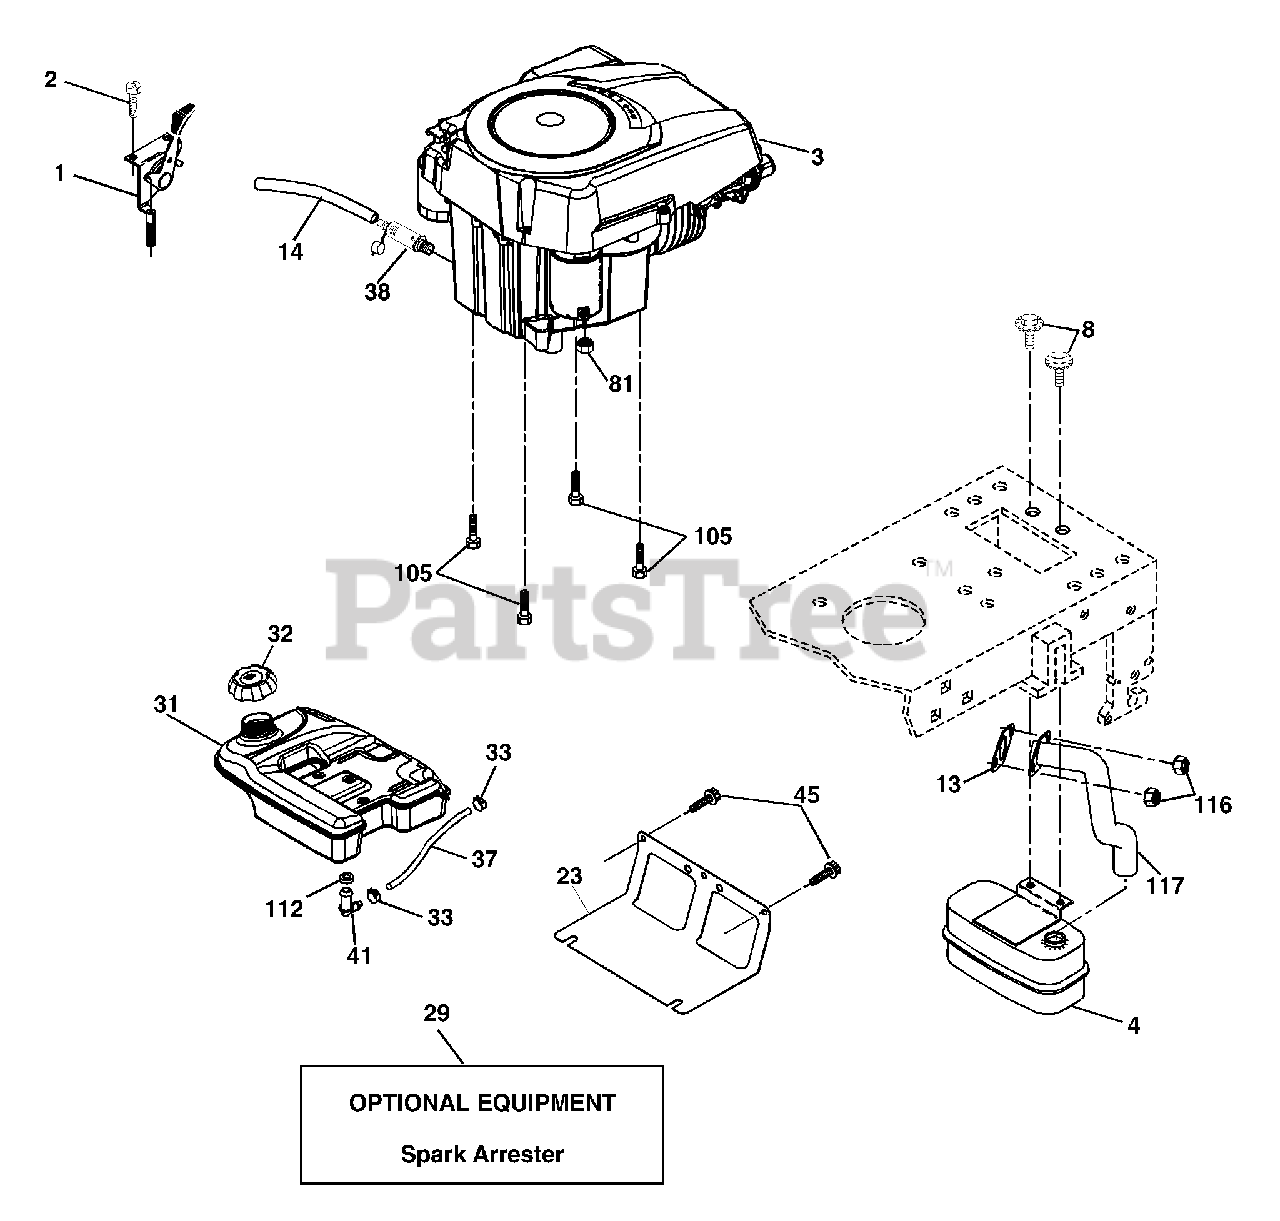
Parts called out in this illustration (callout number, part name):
1	Control Throttle/Choke Flag
2	Screw Hex Thd Cut 1/4-20 x 1/2
8	Bolt 5/16-18 unc x 3/4
13	Gasket Eng
14	Tube Drain Oil Easy
23	Shield Brn/Dbr Guard
29	Kit Spark Arrestor (Flat Scrn)
32	Cap Asm Fuel
33	Clamp Hose Black
37	Line Fuel 64"
38	Plug Drain Oil Easy
41	Stem Tank Fuel
45	Screw Hex wsh Thdr 3/8-16 x 3/4
81	Nut Keps Hex 1/4-20
105	Screw 3/8-16 x 1
112	Bushing
116	Nut Hex Flange Toplock M8-1.25
117	Tube Exhaust
